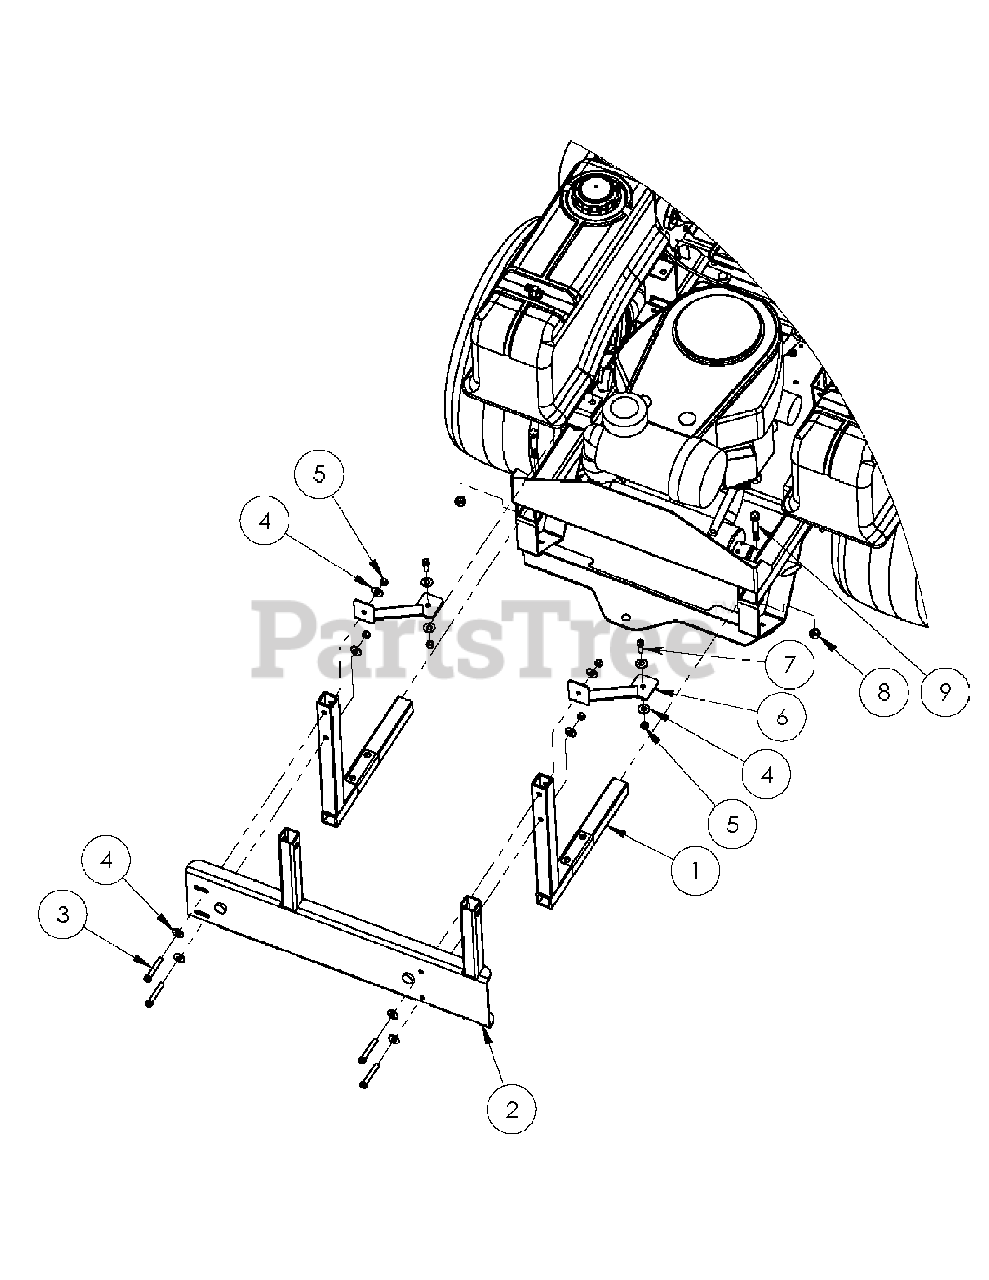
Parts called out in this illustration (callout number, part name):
1	SIDE SUPPORT
2	CATCHER MOUNTING PANEL
3	CAP SCREW 3/8-16 X 2 1/2" LONG
4	3/8" FLAT WASHER
5	HEX NUT, NYLON INSERT 3/8"-16
7	CAP SCREW 3/8-16 X 1" LONG
8	EXISTING HARDWARE
9	EXISTING HARDWARE
